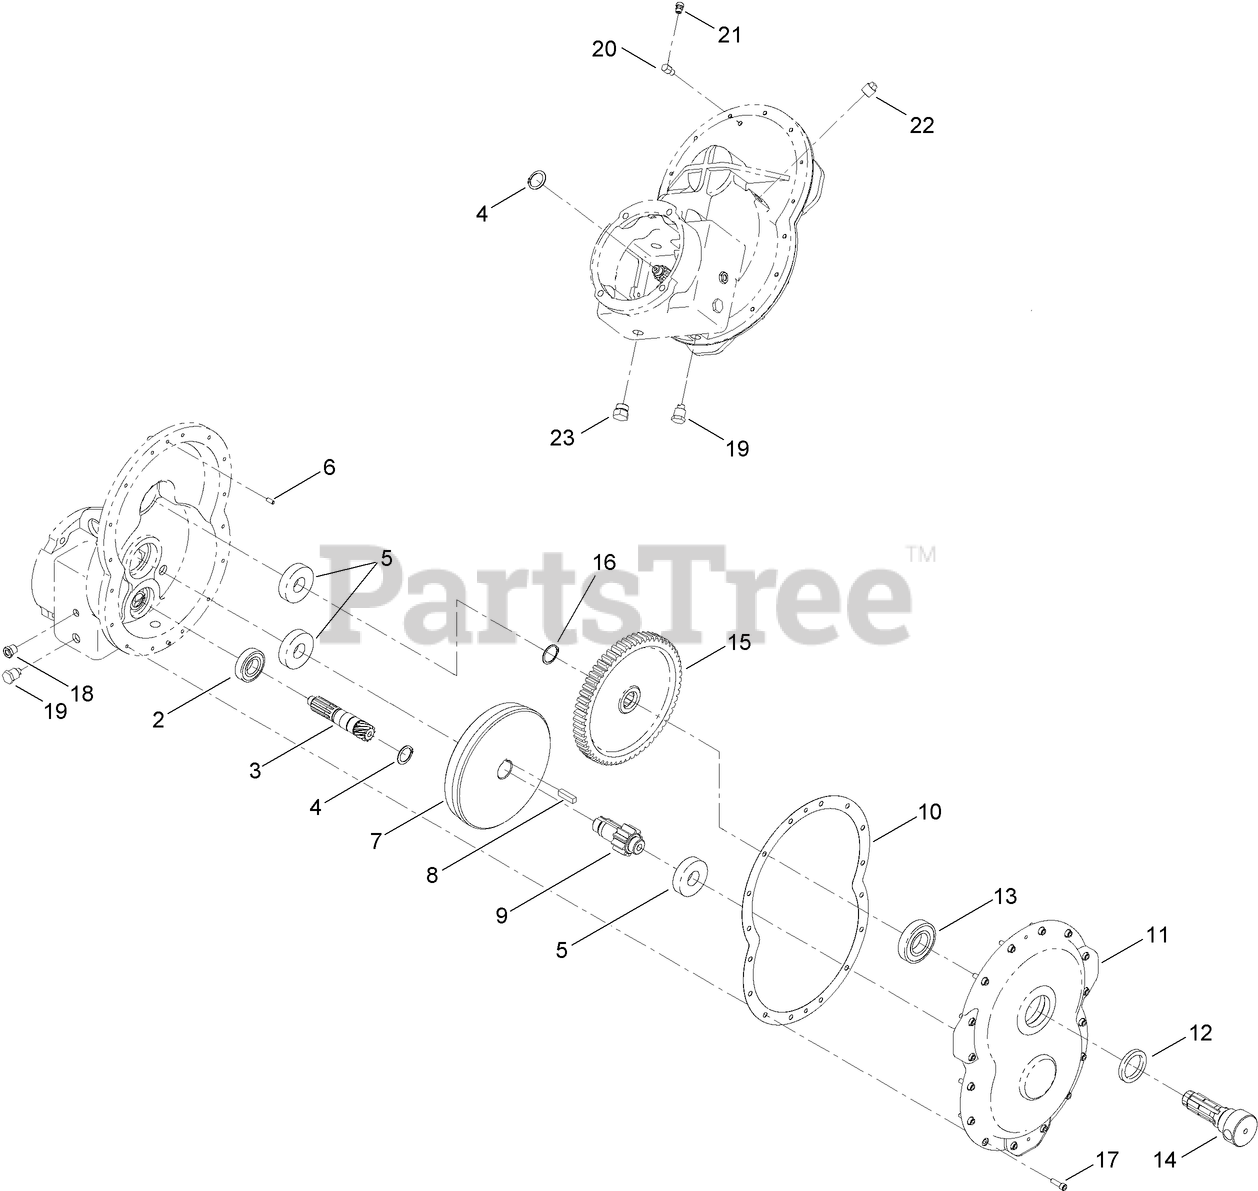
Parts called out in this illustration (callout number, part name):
2	BEARING-BALL
3	SHAFT-INPUT, PINION
4	RING-EXTERNAL
5	BEARING-ROLLER
7	GEAR-HELICAL
8	KEY-SQUARE
9	PINION
10	GASKET-GEARCASE
11	COVER-GEARCASE
12	SEAL-SHAFT
13	BEARING-BALL
14	SHAFT-OUTPUT, GEARCASE
15	GEAR-SPUR
16	RING-SNAP, EXTERNAL
17	SCREW-HSH
18	PLUG-SIGHT, OIL
19	PLUG-HH, MAGNETIC
20	ELBOW-CONNECTION
21	BREATHER-ALEMITE
